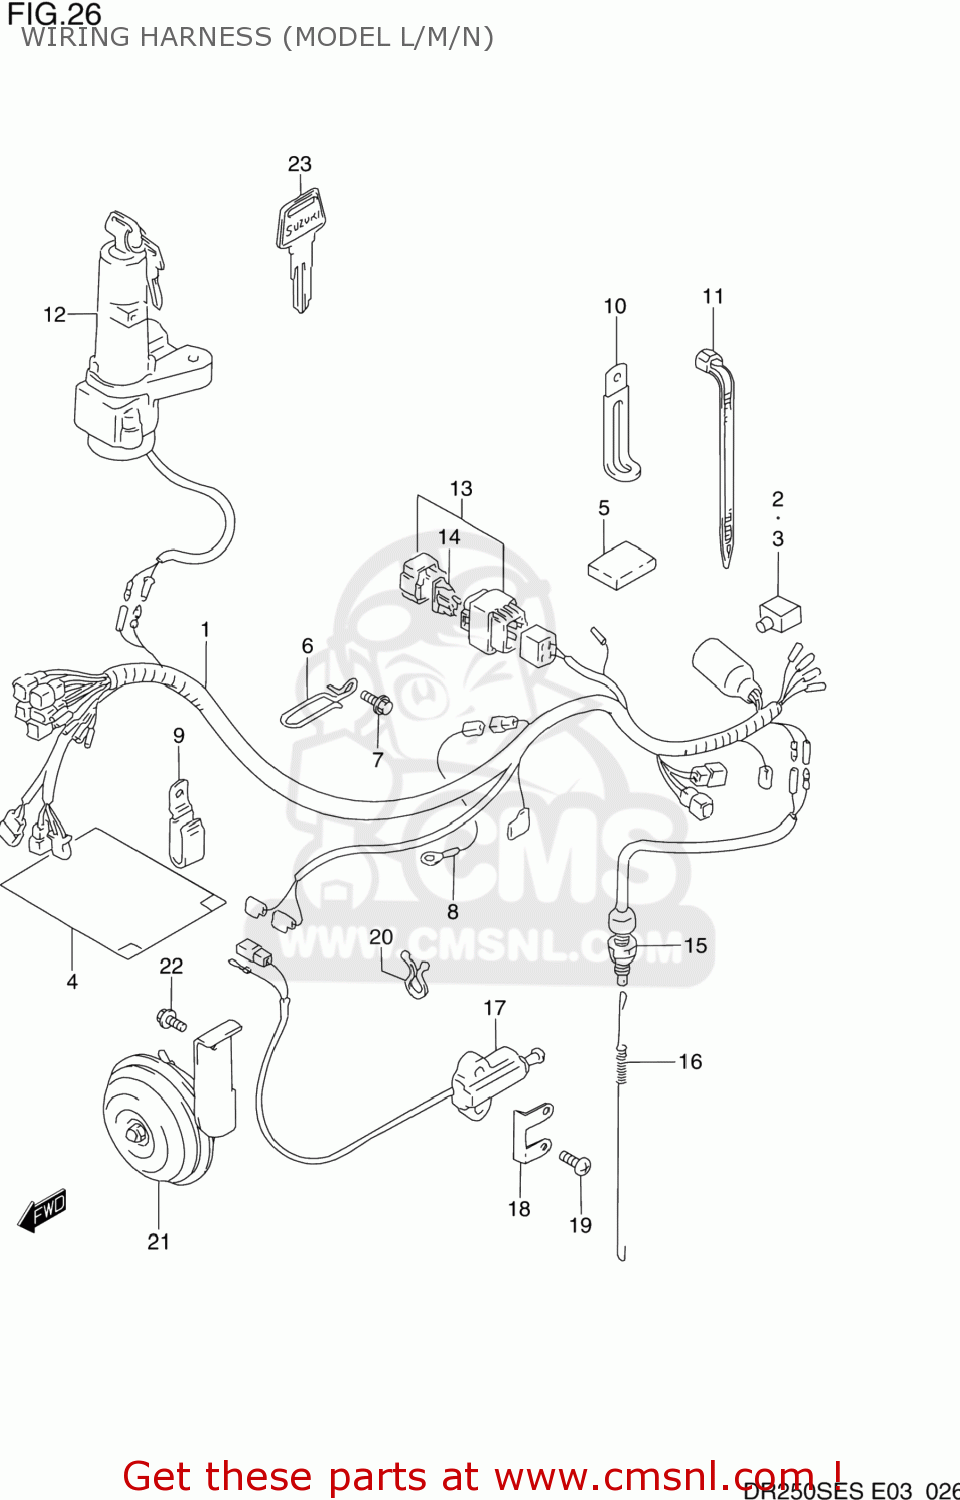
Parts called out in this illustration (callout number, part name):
1	HARNESS,WIRING
2	CAP,BATTERY PLUS TERMINAL
3	CAP,BATTERY PLUS TERMINAL
4	COVER,WIRING HARNESS
5	PROTECTOR(170X95X3.0)
6	GUIDE,WIRING HARNESS
7	BOLT
8	WIRE
9	CLAMP
10	CLAMP
11	CLAMP
12	SWITCH ASSEMBLY,IGNITION
13	BOX ASSY,FUSE
14	FUSE(15A)
15	SWITCH ASSY,STOP LAMP
16	SPRING
17	SWITCH ASSEMBLY,SIDE STAND
18	PROTECTOR,SIDE STAND SWITCH
19	SCREW, CENTER
20	CLIP(ID:11.5)
21	HORN ASSEMBLY
22	BOLT
23	KEY,BLANK
